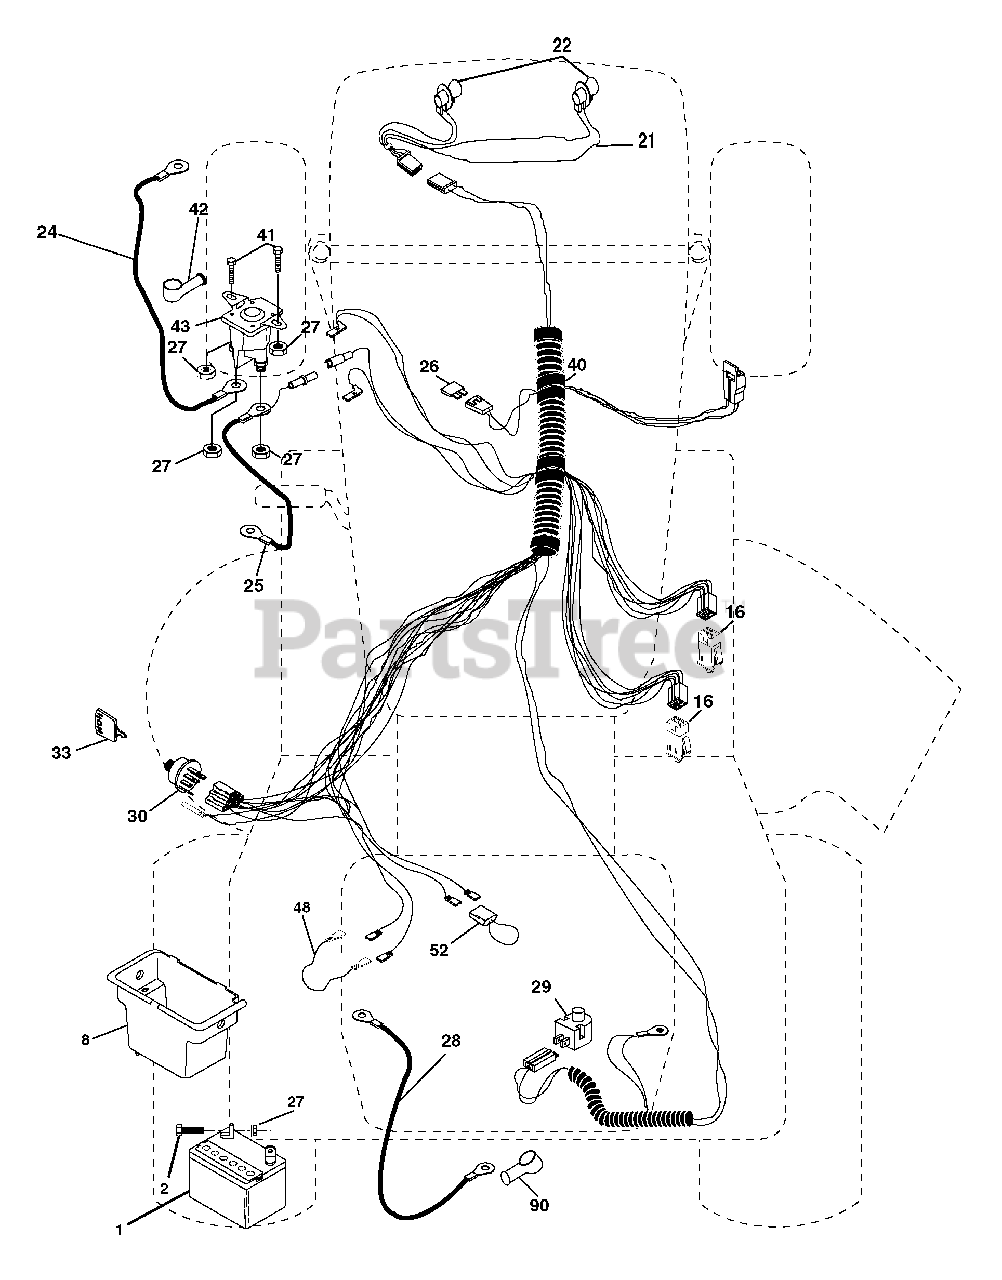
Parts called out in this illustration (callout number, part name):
1	Battery
2	Bolt Hex Hd 1/4-20unc x 3/4
8	Box Battery Fender
16	Switch, Interlock
21	Harness Asm Light W/4152j
22	Bulb Light #1156
24	Cable Battery 6 Ga 11" red
25	Cable Battery 6 Ga w/16 wire red
26	Fuse 20 AMP
27	Nut, Keps Hex 1/4-20 UNC
28	Cable Ground 6 Ga 12" black
29	Switch Plunger Nc Gray
30	Switch Ign
33	Key Ign.
40	Harness Ign
41	Bolt Blk. Fin Hex 1/4-20 Unc x 1/2
42	Cover Terminal Red
43	Solenoid
48	Adapter Ammeter
52	Protection Wire Loop
90	Cover Battery Terminal
